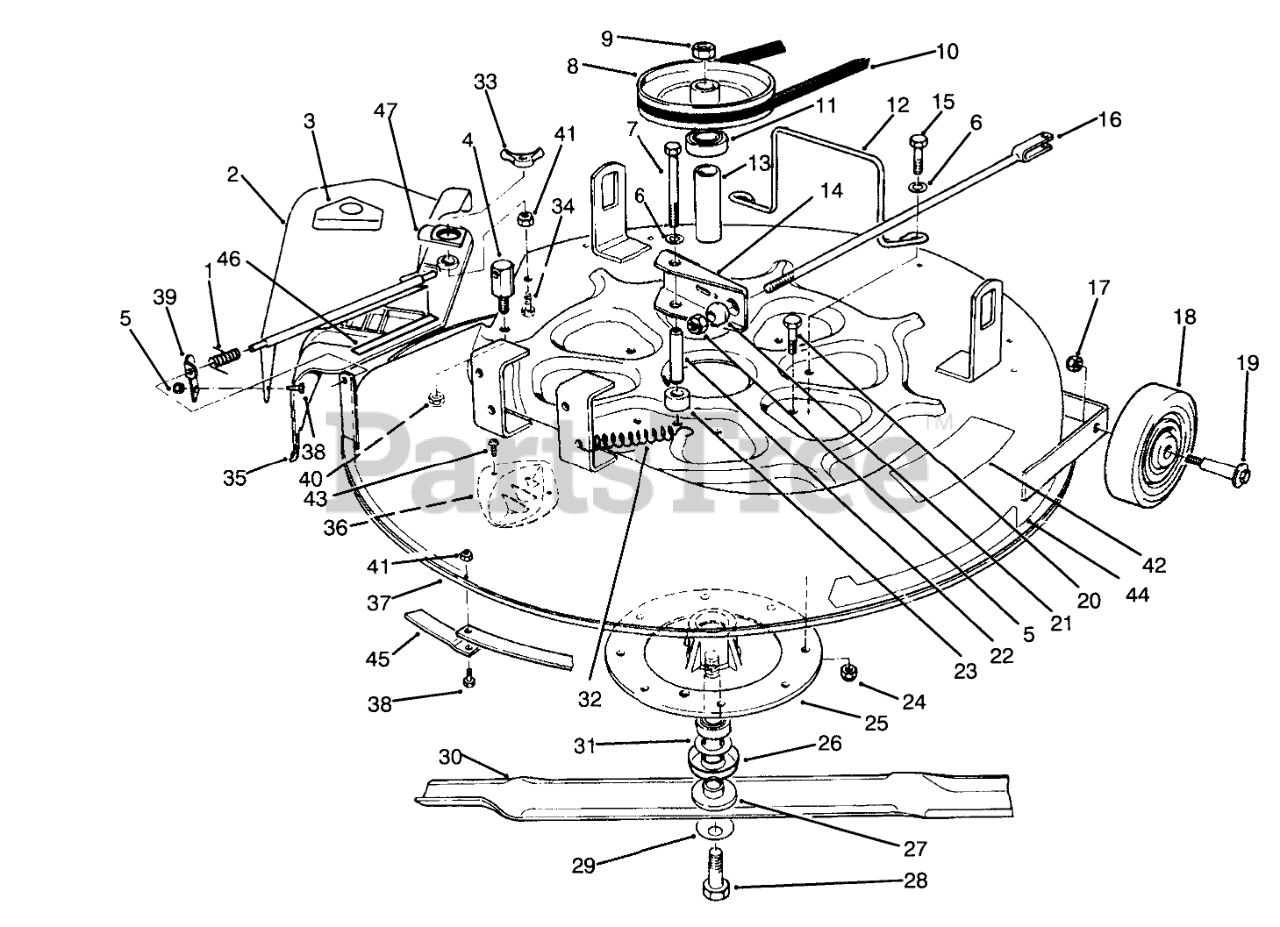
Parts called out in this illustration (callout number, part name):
1	SPRING
2	Deflector (Incl. Ref. #3)
3	DECAL-DANGER
4	POST-PIVOT
5	NUT-HEX
6	WASHER-PLAIN
7	SCREW-HH
8	PULLEY-DECK
9	NUT-HEX
10	V-Belt
11	BEARING-BALL
12	GUIDE-DECK BELT
13	SPACER-BEARING
14	DECK BRAKE ASSEMBLY
15	SCREW-HH
16	DECK BRAKE ROD WA
17	NUT-LOCK, NI
18	WHEEL-DECK
19	BOLT-WHEEL
20	SCREW-HH
21	BALL-SWIVEL, STOP
22	POST-BRAKE MTG
23	SPACER-DECK BRAKE
24	NUT-LOCK, NI
25	CASTING-SPINDLE
26	SHIELD-BEARING
27	SHAFT-SPINDLE
28	SCREW-HH
29	WASHER-BELLEVILLE
30	Blade
31	SPACER
32	SPRING-EXTENSION
33	Nut-Wing
34	SCREW-HHF
35	COVER- 25" (W/KICKER)
36	KICKER
37	Deck (Incl. Ref. #42)
38	SCREW-HH
39	BRACKET-DEFLECTOR
40	NUT-LOCK, NI
41	NUT-LOCK, NI
42	DECAL - DANGER
43	SCREW-PPH
44	DECAL - RECYCLER 25"
45	25" RECYCLER RING (BLACK)
46	DECAL-DANGER, DEFLECTOR
